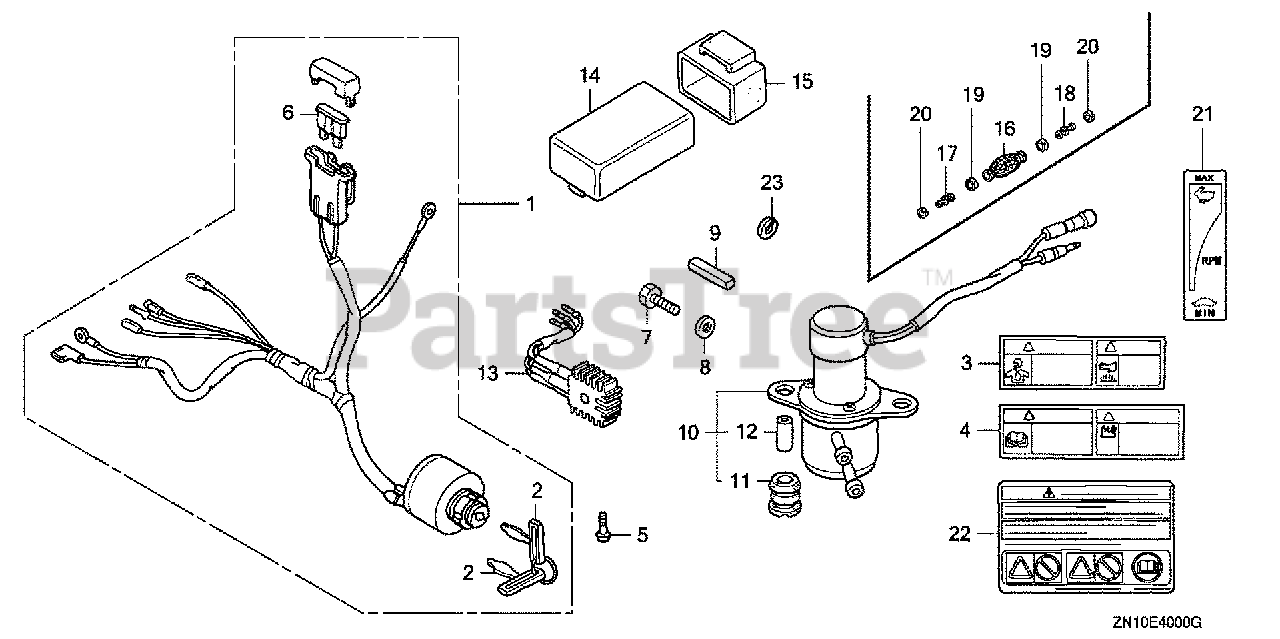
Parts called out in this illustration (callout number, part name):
13	RECTIFIER ASSY. (10A)
14	CONTROL UNIT, VALVE
15	CUSHION, VALVE CONTROL UNIT
